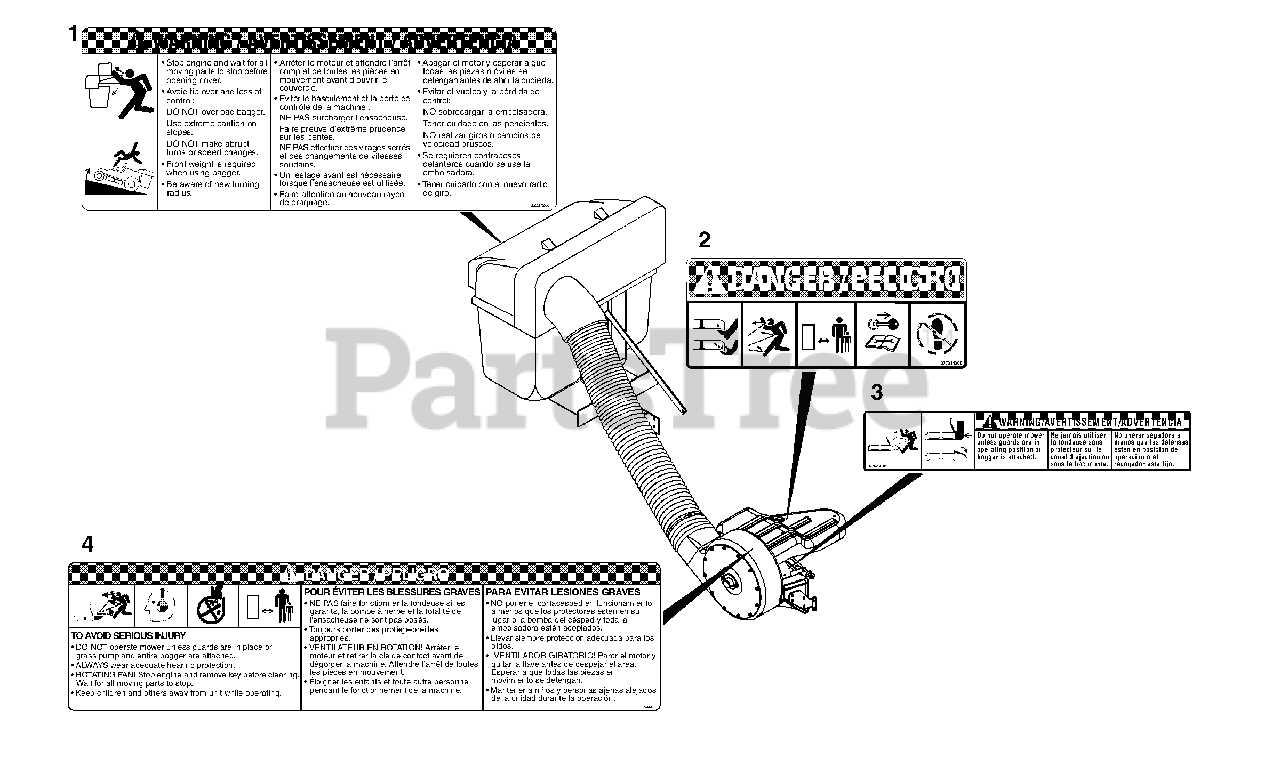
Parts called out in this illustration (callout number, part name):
1	Decal-Bagger Hood, EZR
2	Decal, Mower Pan Head Danger
3	Decal, Warning
4	Decal-Caution, Grass Pump
